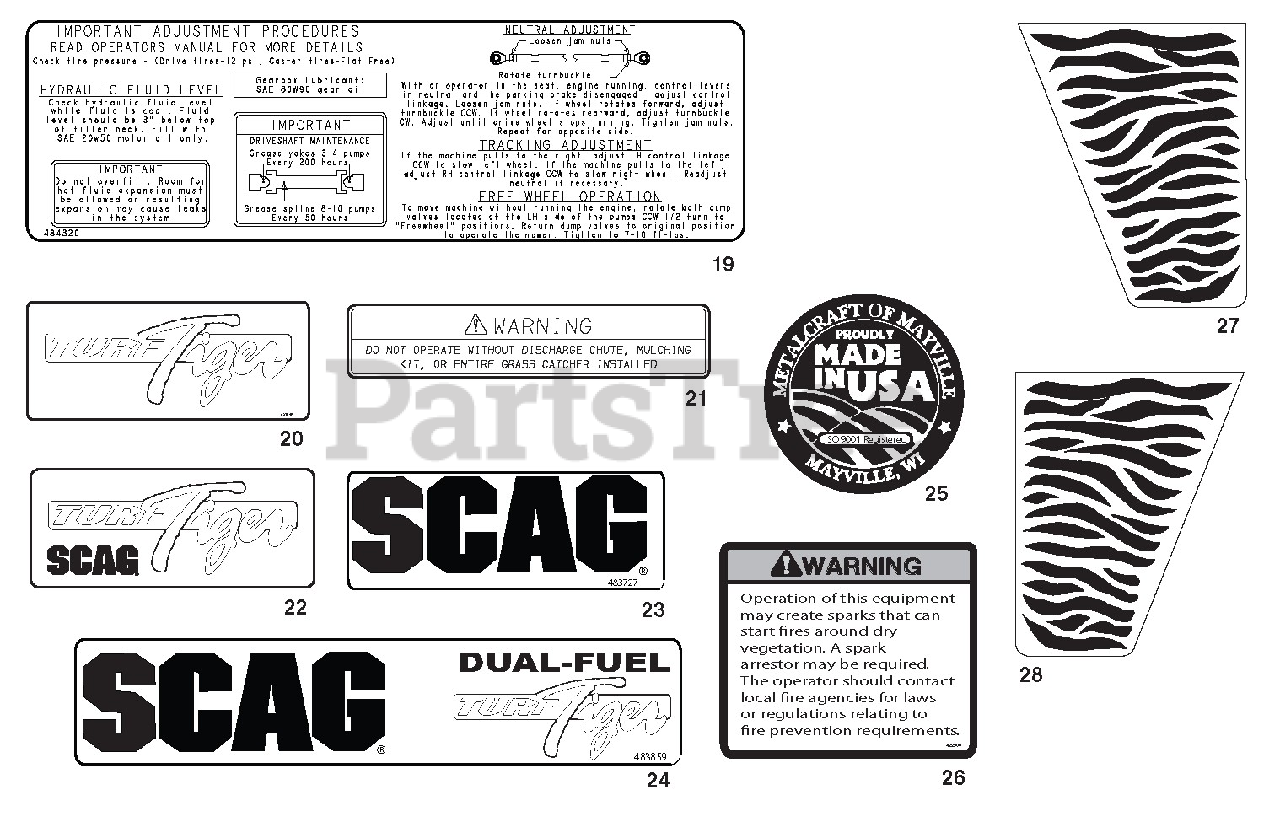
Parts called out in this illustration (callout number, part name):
19	Decal, Checks and Adjustments
20	Decal, Turf Tiger
21	Decal, Warning
22	Decal, Turf Tiger
23	Decal, Scag Logo
24	Decal, Scag Dual-Fuel
25	Decal, Metalcraft-Made In USA
26	Decal, Warning Spark Arrestor
27	Decal, Stripes-RH
28	Decal, Stripes-LH
